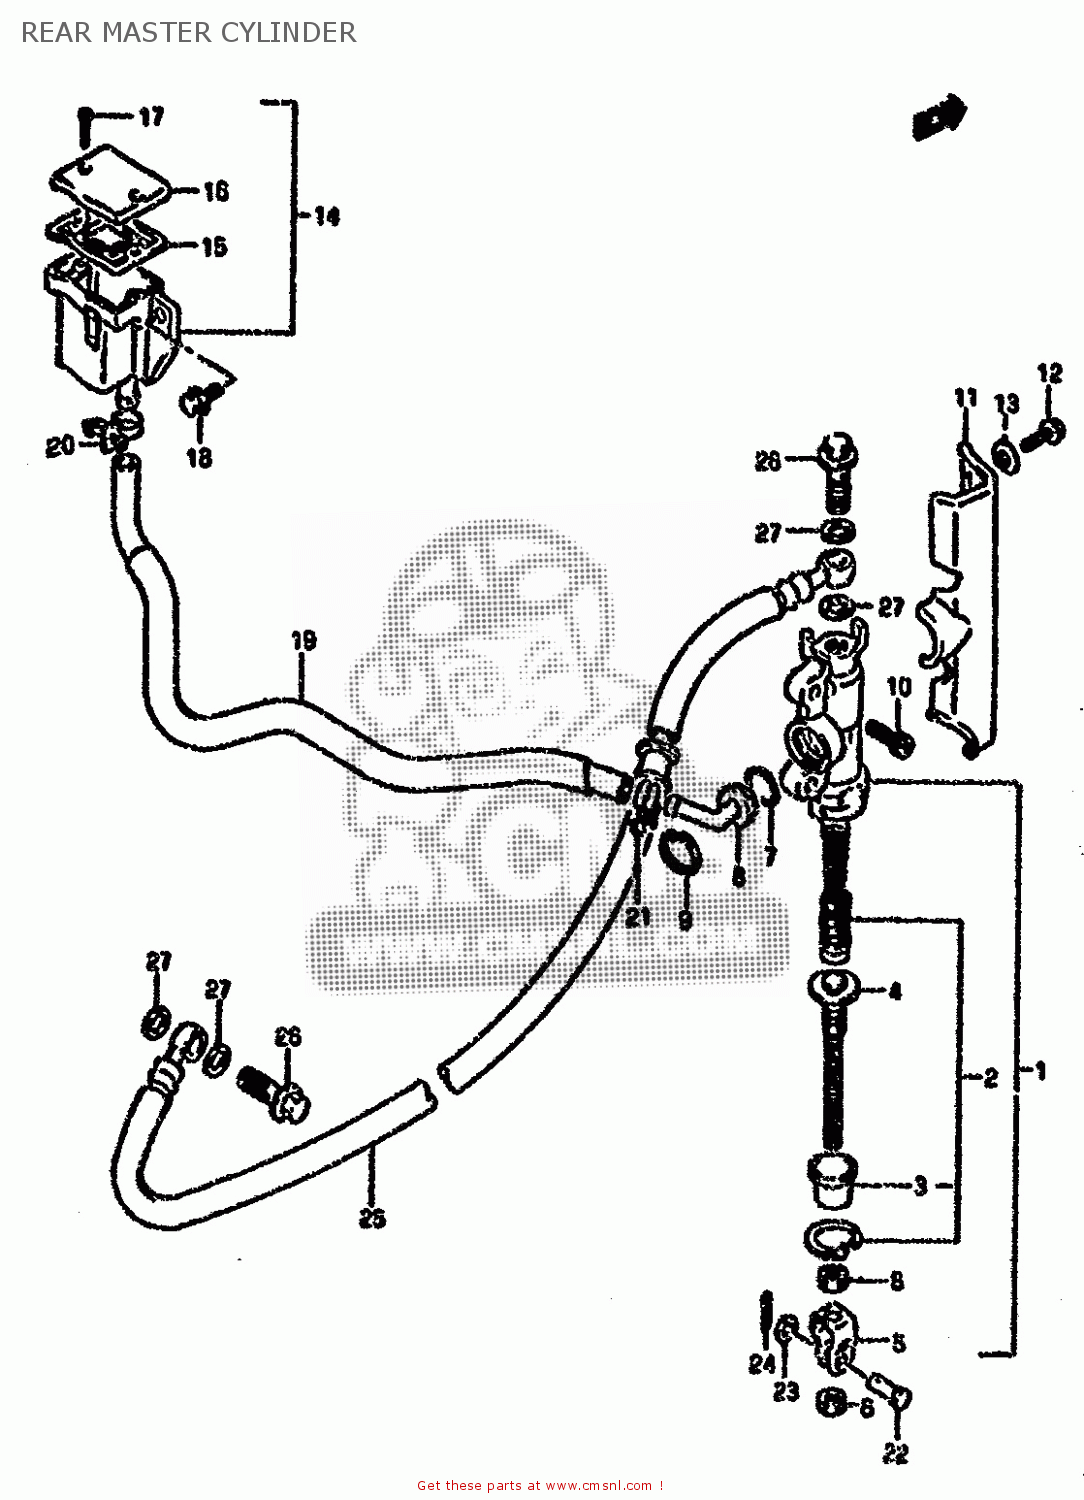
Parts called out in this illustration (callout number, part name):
1	CYLINDER ASSEMBLY,REAR MASTER
2	PISTON/CUP SET
3	BOOT
4	ROD,PUSH
5	YOKE
6	NUT
7	O RING
8	CONNECTOR
9	CIRCLIP
10	BOLT
11	COVER,FRAME MASTER CYLINDER
12	SCREW 6X12
13	WASHER
14	TANK ASSY,RESERVOIR
15	DIAPHRAGM
16	CAP
17	SCREW
18	BOLT
19	HOSE,RESERVOIR TANK
20	CLIP
21	CLAMP
22	PIN
23	WASHER
24	PIN
25	HOSE,RR BRAKE
26	BOLT,UNION
27	WASHER(10X15X1.5)
